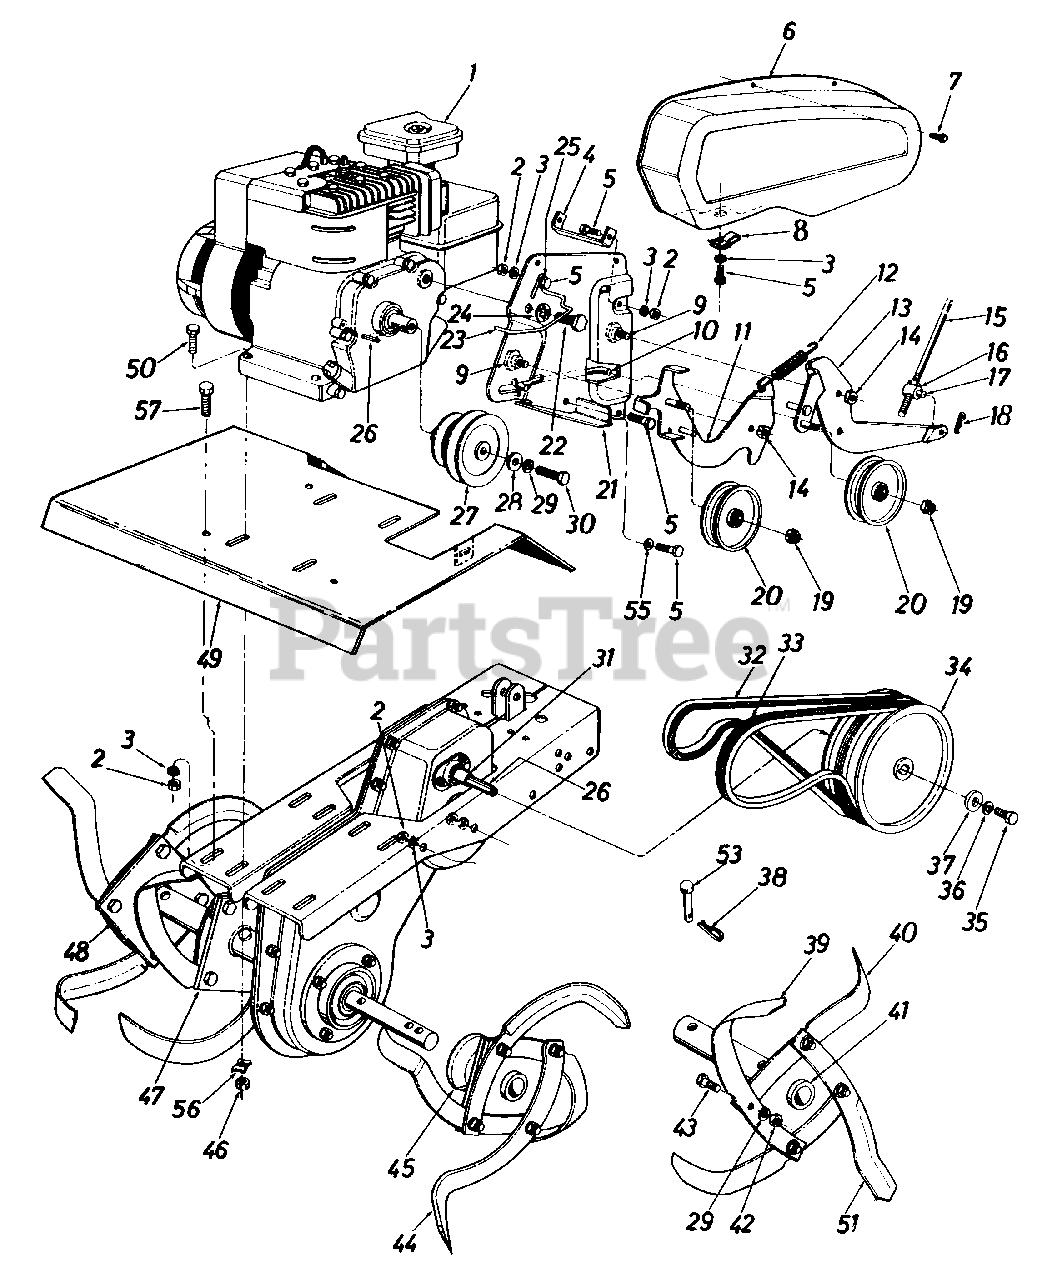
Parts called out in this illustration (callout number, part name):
1	Engine
2	Hex Nut 1/4-20 Thd.
3	L-Wash. 1/4" Scr.
4	Support Bracket
5	Hex Scr. 1/4-20 x .75" Lg.
8	"U"-Type Speed Nut
9	Shoulder Bolt .625 Dia. x .170" Lg.
10	Control Rod
11	Reverse Idler Brkt. Ass'y.
12	Spring - Idler Brkt.
13	Forward Idler Brkt. Ass'y.
14	Hex Cent. L-Nut 3/8-16 Thd.
15	Clutch Control Rod
16	Speed Nut 3/8-24 Thd.
18	Inter. Cotter Pin 1/2" Dia.
19	Hex Jam Nut 3/8-24 Thd.
20	Fl-Idler w/Flanges 3.12 O.D. x .75
21	Clutch Mounting Plate
22	Hex Bolt 1/2-20 x .75 Spec.
23	Belt Guard Rod
24	Internal L-Wash. 1/2" I.D.
25	Fl-Wash. 1/4" I.D.
26	Sq. Key 3/16 x 1.50" Lg.
27	Engine Pulley
28	Fl-Wash. 3/8" I.D. x 1.00" O.D.
29	L-Wash. 3/8" I.D.
30	Hex Bolt 3/8-24 x 1.25" Lg.
31	Spacer .635 I.D. x .88 O.D. x 1.035 Lg.
32	"V"-Belt 1/2" x 41" Lg. Reverse
33	"V"-Belt 1/2" x 37" Lg. Forward
34	Chain Case Pulley 6.0" Dia.
35	Hex Bolt 5/16-18 x 1.25 Lg. Spec.
36	Shake-Proof Wash.
37	Fl-Wash. 5/16" I.D. x 1.120 O.D.
38	Internal Cotter Pin 1/2" Dia.
43	Hex Bolt 3/8-24 x 1.25" Lg.
44	Inner Tine Ass'y. Comp. - L.H.
45	Inner Tine Adapter Ass'y.
46	Hex Nut 5/16-18 Thd.
47	Inner Tine Ass'y. Comp. - R.H.
48	Outer Tine Ass'y. Comp. - R.H.
49	Tine Shield
50	Hex Scr. 5/16-18 x 1.50" Lg.
51	Outer Tine Ass'y. Comp. - L.H.
53	Clevis Pin
55	Bell-Wash.
56	Shake-Proof Wash.
57	Hex Scr. 1/4-20 x .75" Lg.
